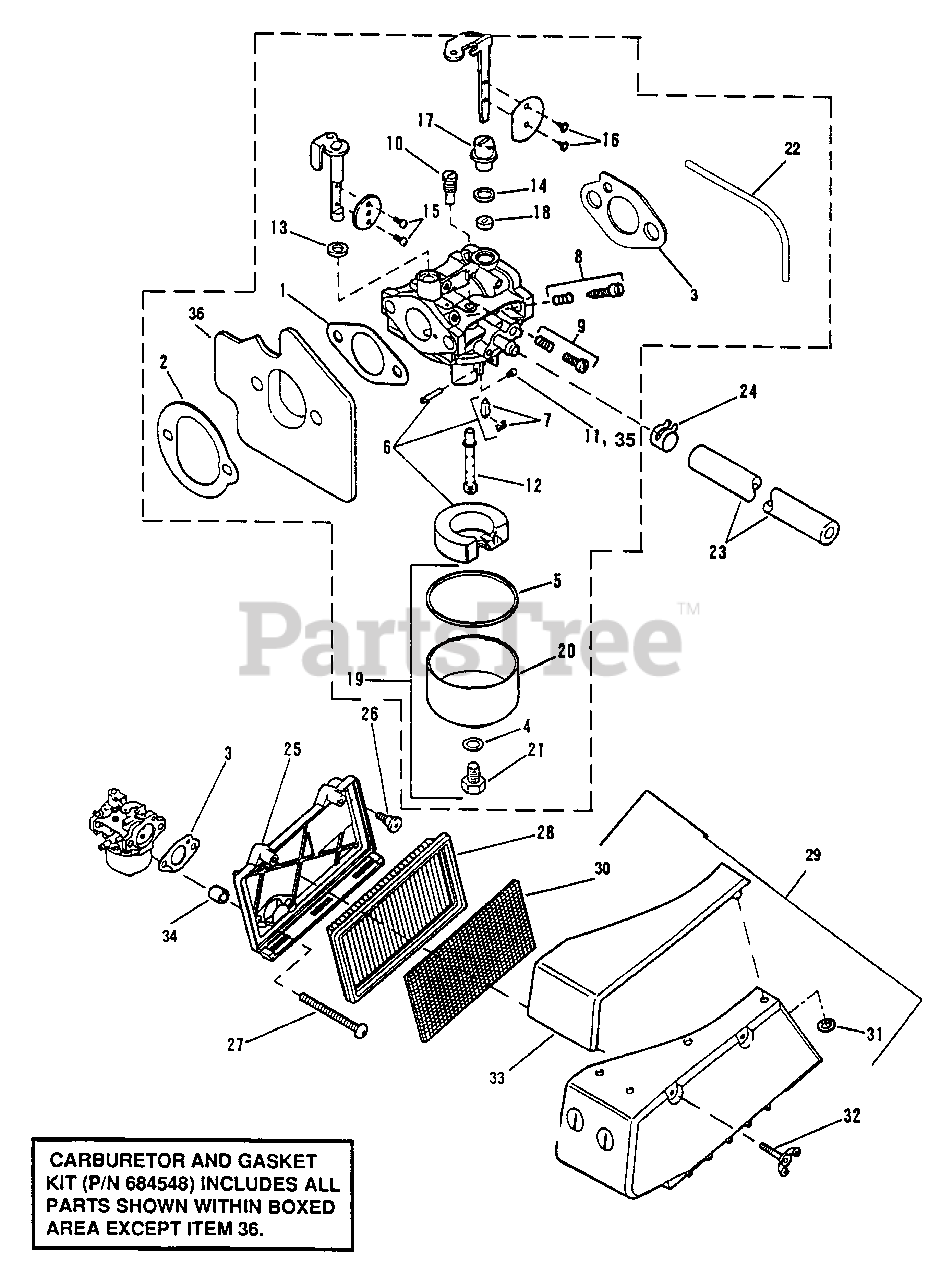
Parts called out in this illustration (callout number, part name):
1	Gasket-Carburetor to Spacer
2	Gasket-Spacer to Engine
3	Gasket-Air Filter Base
4	Gasket-Bowl Retainer
5	Gasket-Fuel Bowl
6	Float & Needle Kit (Inc. 7)
7	Needle & Clip
8	Idle Needle & Spring Kit
9	Idle Speed Kit
10	Pilot Jet
11	Main Jet
12	Nozzle
13	Throttle Shaft Seal
14	Choke Shaft Seal
15	Screw-Throttle Valve
16	Screw-Choke Valve
17	Upper Choke Shaft Pivot
18	Lower Choke Shaft Pivot
19	Bowl Kit (Inc. 20-21)
20	Fuel Bowl
21	Screw-Bowl Retainer
22	Carb Vent
23	Gas Line
24	Hose Clamp
25	Air Filter Base
26	Bolt
27	Screw-Carburetor to Engine
28	Air Filter
29	Air Filter Cover Assy (Inc. 30-33)
30	Pre-Filter
31	Pushnut
32	Wing Screw
33	Air Box Cover
34	Spacer
35	Main Jet-High Altitude
36	Spacer
